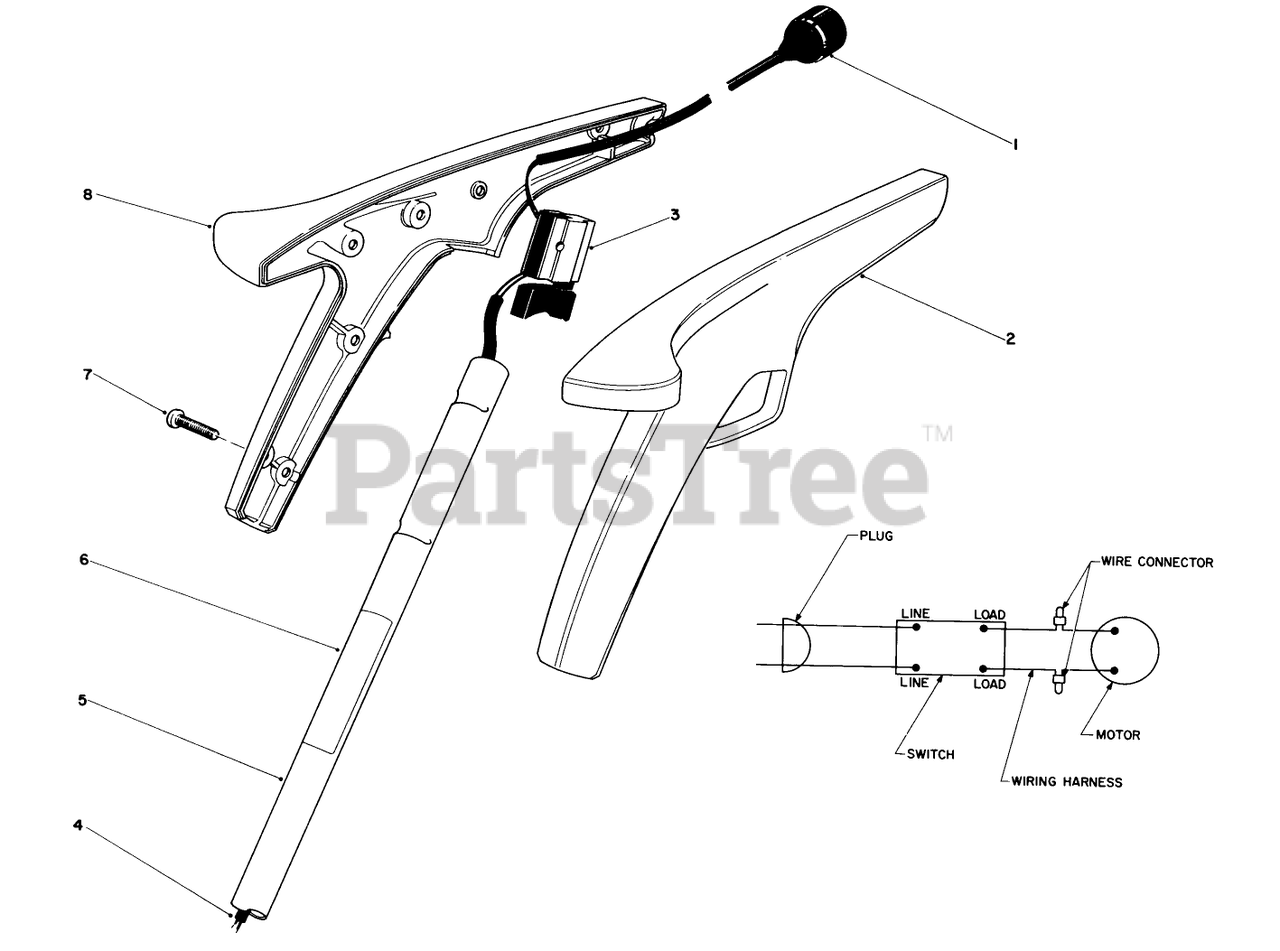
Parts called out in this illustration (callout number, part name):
1	Cord-Power
2	LH HANDLE GRIP
3	SWITCH SINGLE SPEED
4	WIRING HARNESS
6	REP. SERIAL PLT
7	#8 X .625" PHILPS PAN H
8	Grip-Right Hand
